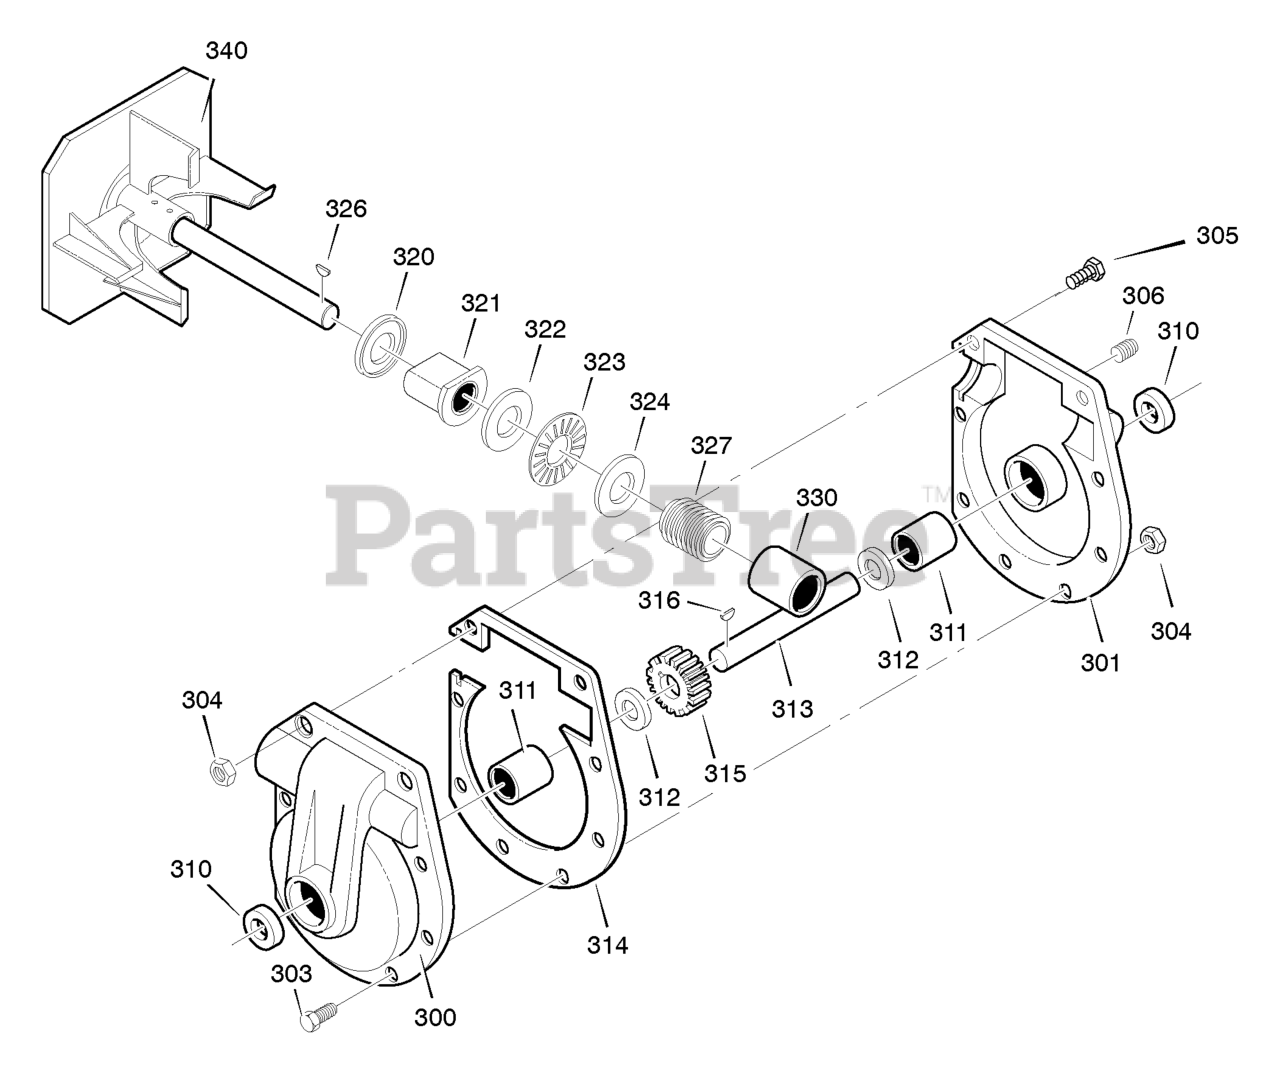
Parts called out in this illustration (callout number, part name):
300	CASE, GEAR, RH
301	CASE, GEAR, LH
303	SCREW, 5/16-24 x 1.00
304	NUT, 5/16-24
305	SCREW, 5/16-24 x 1.50
306	PLUG, PIPE 0.25-18
310	SEAL, OIL
311	BEARING, SLEEVE
312	WASHER, FLAT
313	SHAFT, AUGER OUTPUT
314	GASKET, GEAR BOX
315	WORM GEAR
316	KEY, WOODRUFF #91
320	RING, QUAD 0.924 ID
321	BEARING, FLANGE
322	WASHER, FLAT
323	BEARING, ROLLER
324	WASHER, FLAT
330	BEARING, SLEEVE
340	IMPELLER
